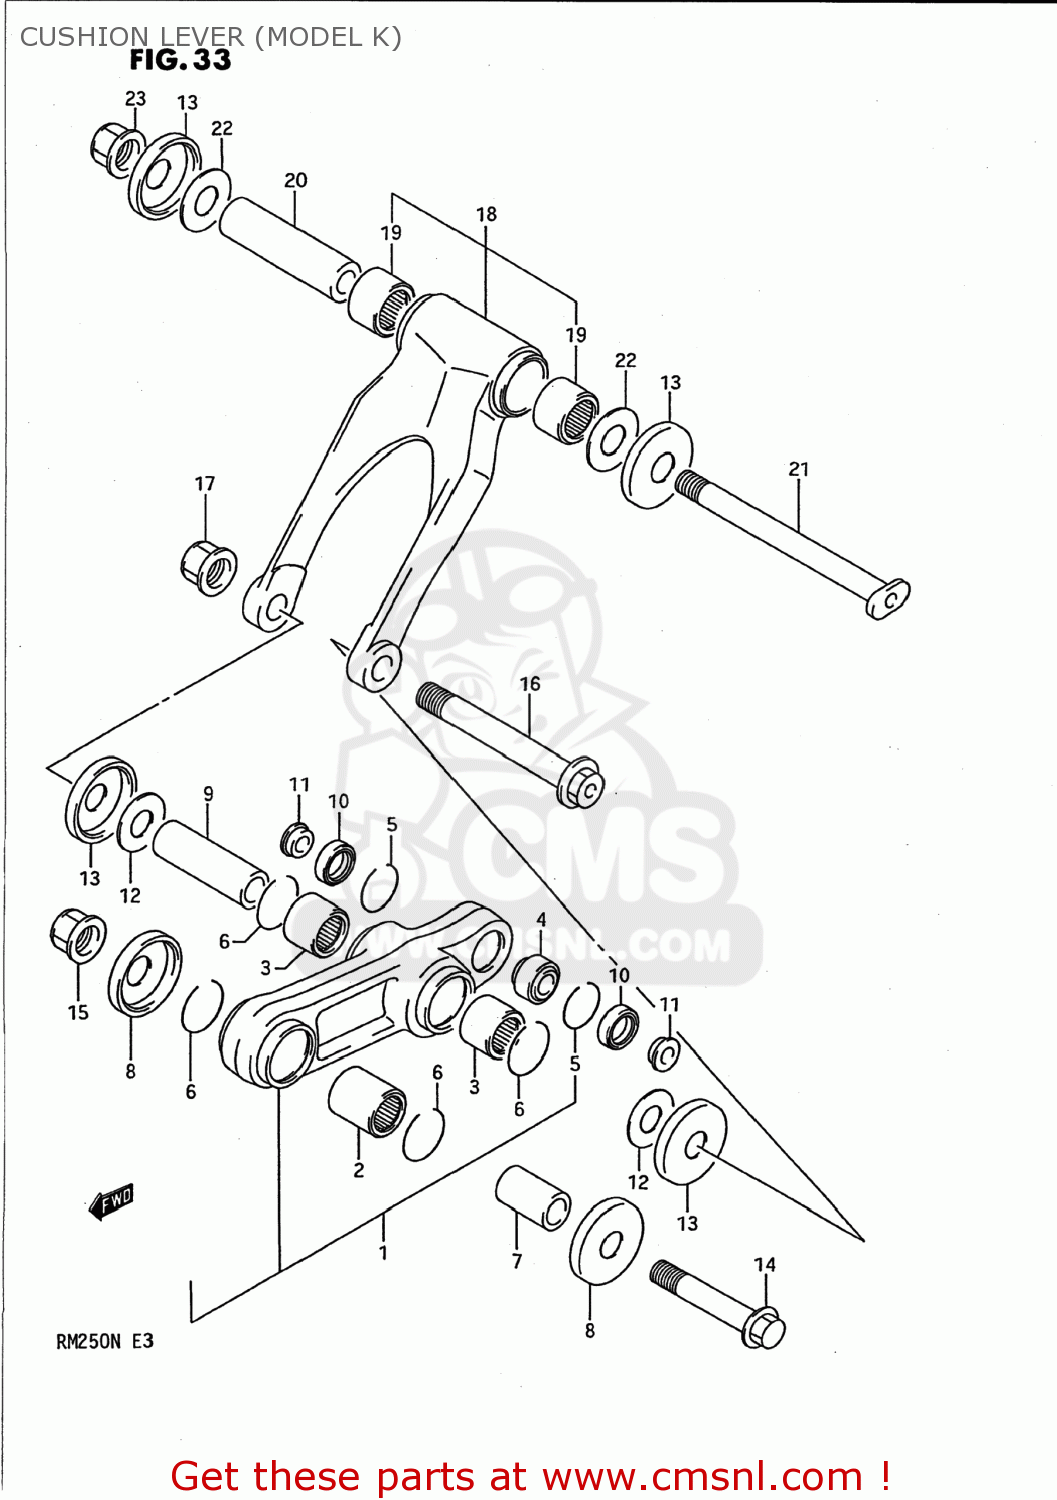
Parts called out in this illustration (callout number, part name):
1	LEVER SET,REAR CUSHION
2	BEARING(20X27X25)
3	BEARING(20X27X20)
4	BEARING,RR CUSHION LEVER
5	RING
6	CIRCLIP
7	SPACER,REAR CUSHION LEVER
8	SEAL,REAR CUSHION LEVER
9	SPACER,REAR CUSHION LEVER
10	SEAL,OIL(17X24X3)
11	COLLAR
12	WASHER
13	SEAL,RR CUSHION LEVER
14	BOLT,RR CUSHION LEVER FR
15	NUT 12MM
16	SHAFT,REAR CUSHION LEVER
17	NUT
18	LEVER SET,REAR CUSHION
19	BEARING(20X27X20)
20	SPACER,RR CUSHION ROD
21	BOLT,REAR CUSHION ROD
22	WASHER
23	NUT
